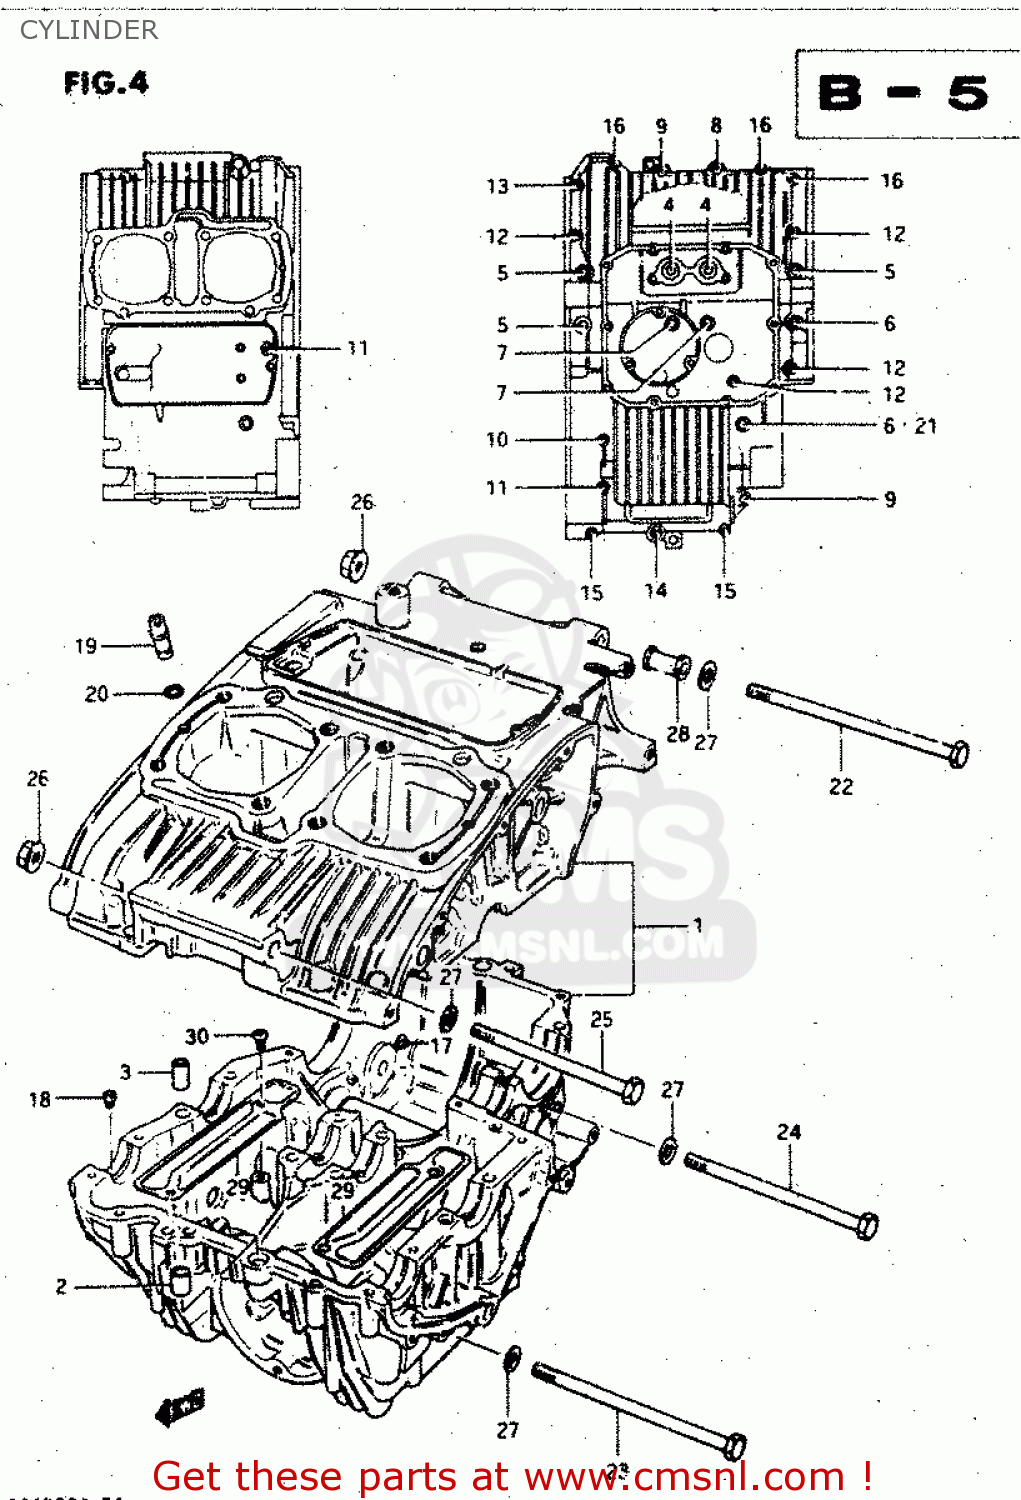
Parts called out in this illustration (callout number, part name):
1	CYLINDER
2	STUD
3	PIN
4	GASKET (T:1.2) (MCA)
5	O RING(D:2,ID:74)
